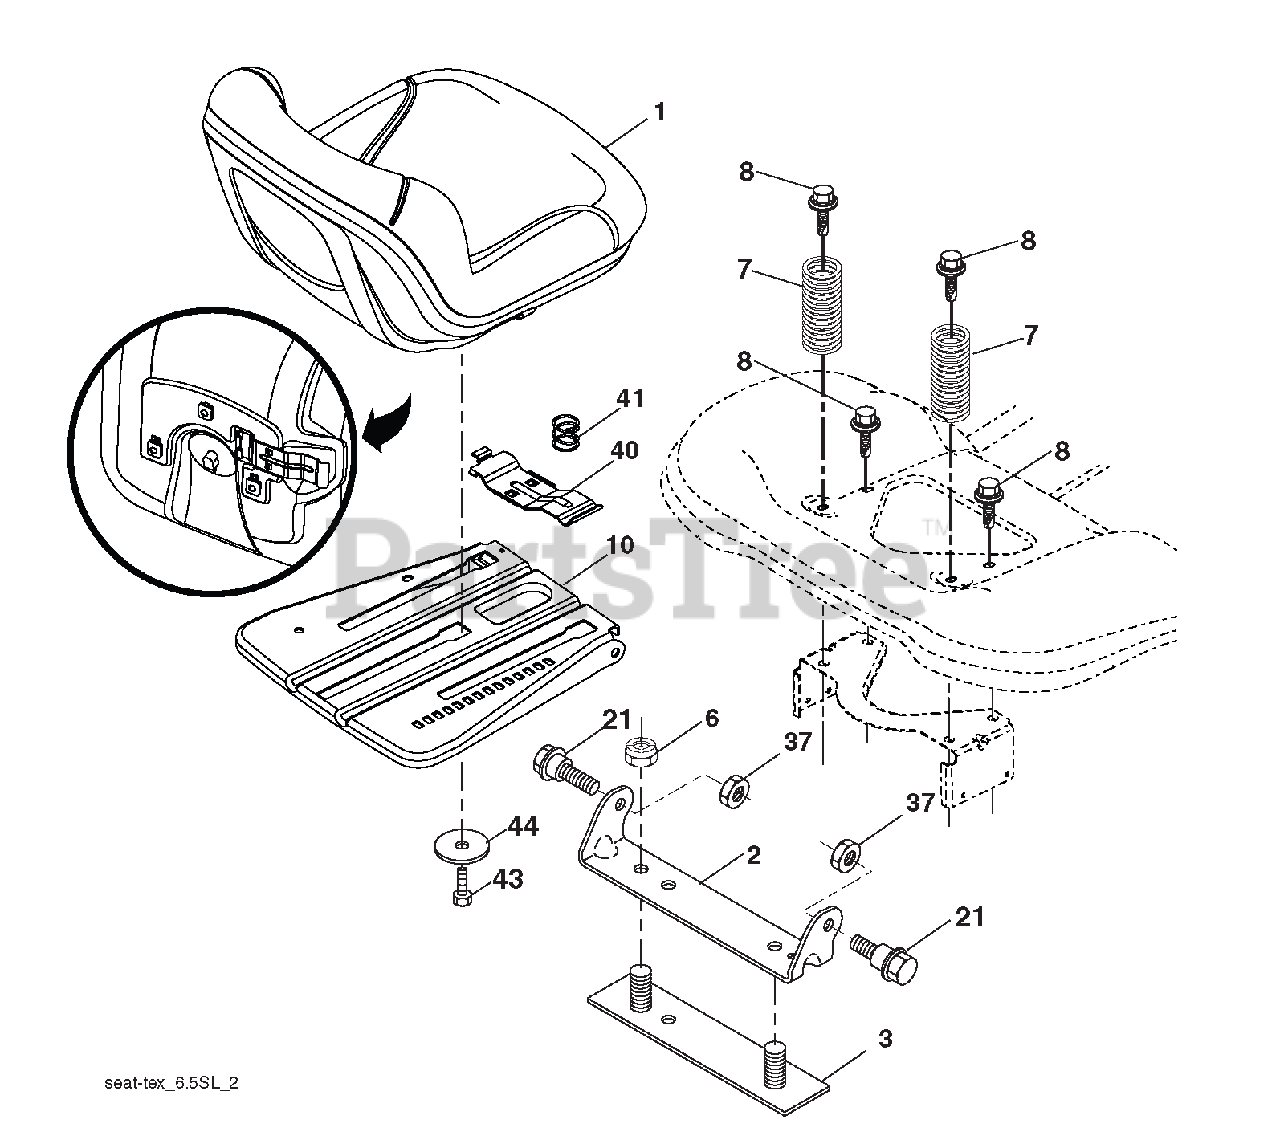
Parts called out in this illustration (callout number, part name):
1	SEAT.TA150.KB/SLD.BLK.ARIENS
2	BRACKET.PIVOT.FENDER.2002
3	STRAP ASM.FENDER.94
6	Locknut, Washer Insert 3/8-16
7	SPRING.SEAT.CPRSN.2.250.BLK.ZI
8	BOLT.5/16-18UNCX3/4 W/SEMS.BLK
10	PAN ASM.SEAT.3PT.
21	BOLT.SHLD.5/16-18 UNC-2A.BLK D
37	Locknut, Washer Insert 5/16-18
40	HANDLE.SLIDE.SEAT.TEX.MILSCO
41	SPRING.LATCH.SEAT.TEX
43	BOLT.FIN.HEX.3/8-16UNC X 3/4
44	WASHER.13/32 X 2 3/8 X 12GA.
